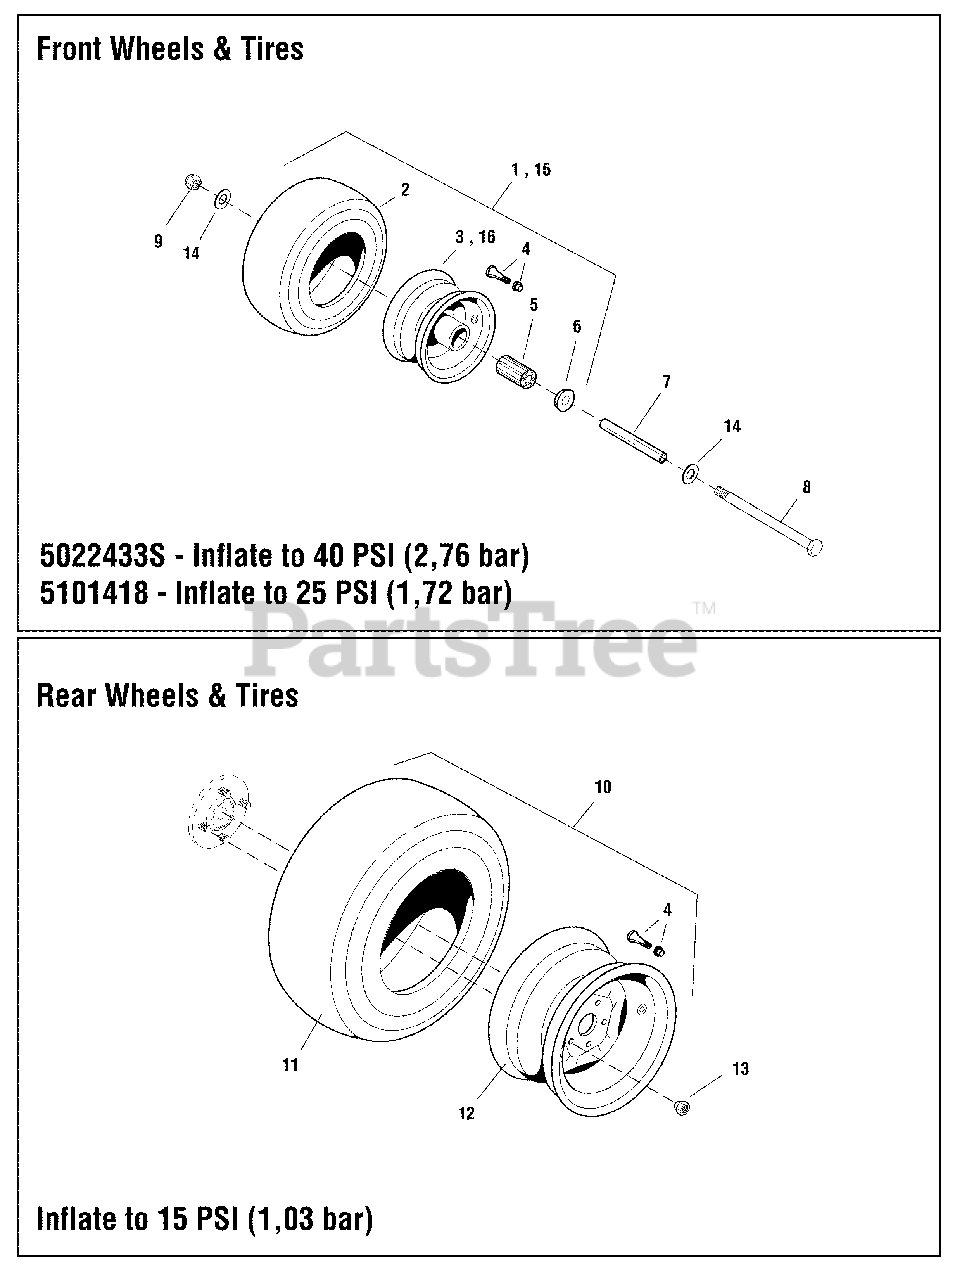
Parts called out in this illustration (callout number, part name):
1	WHEEL, CASTER, 11X4.0-5 WHITE
2	TIRE, 11 X 4.0-5 (TIRE ONLY)
3	WHEEL ASSEMBLY, 11X4.0X5 SILVER
4	VALVE STEM & CAP, AIR .453DIA 0.88LG
5	BEARING, ROLLER
6	RETAINER, BEARING
7	CASTER AXLE DDSH
8	BOLT, 1/2-13 X 6-1/2 GD8 YZ
9	NUT, 1/2-13 HEX NYLON LOCK
10	TIRE ASSM, 20X8.00-10NHS, TURF MASTER
11	TIRE, 20X 8.0 X 10 (TIRE ONLY)
12	WHEEL ASSEMBLY, 20 X 8.0 X 10
13	NUT, 1/2-20, FOR WHEEL BOLT SILVER
14	WASHER, 1/2 SAE
15	WHEEL, CASTER, 11 X 4.0-5 SILVER BEAD LO
16	WHEEL ASSEMBLY, COMPLETE
